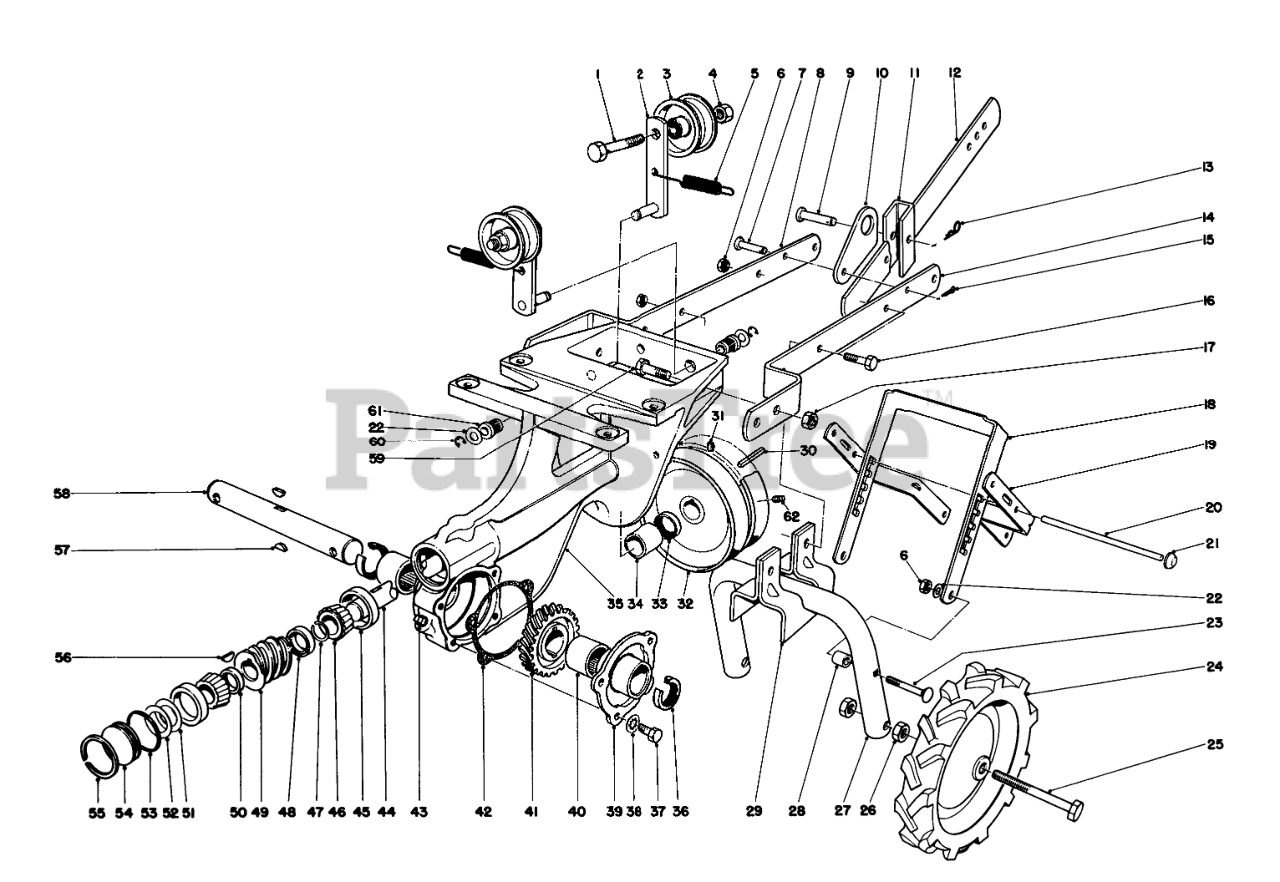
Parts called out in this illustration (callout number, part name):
1	SCREW-HH
2	Idler Arm
3	PULLEY IDLER
4	NUT-LOCK, CONE
5	TENSION SPRING
6	NUT-LOCK, CONE
7	PIN-CLEVIS
8	Drawbar R.H.
9	CLEVIS
10	Latch-Depth Gauge
11	DEPTH GUAGE BRKT
12	Depth Gauge
13	PIN-COTTER, HAIR
14	Drawbar L.H.
15	PIN-COTTER
16	SCREW-HH
17	NUT-KEPS
18	Lever Wheel Adjustment
19	HANDLE SUPPORT
20	Shaft-Wheel Adjustment
21	PUSH ON
22	WASHER-PLAIN
23	BOLT-CARR
24	Wheel
25	Wheel Bolt
26	NUT-HEX
27	Axle Yoke
28	Spacer
29	Saddle Yoke
30	KEY-SQUARE
31	SCREW-SQH
32	WORM SHAFT PULLEY
33	SEAL-OIL
34	BUSHING
35	Chassis
36	SEAL-OIL
37	1/4-20 X 5/8 CAPSCREW
38	WASHER-LOCK
39	Cover
40	Needle Bearing
41	WORM WHEEL
42	GASKET
43	PLUG-PIPE, SQH
44	WORM SHAFT
45	BEARING-ROLLER, CUP
46	BEARING-CONE
47	RETAINER RING
48	Spacer Rear
49	WORM GEAR
50	Spacer Front
53	O-RING
55	INTRNL RETAINING RING
56	KEY-WOODRUFF
57	KEY-WOODRUFF
58	WORM WHEEL SHAFT
59	SCREW-HH
60	RING-RETAINING, EXT
61	SEAL-FACE, OUTER
62	SCREW-SET
